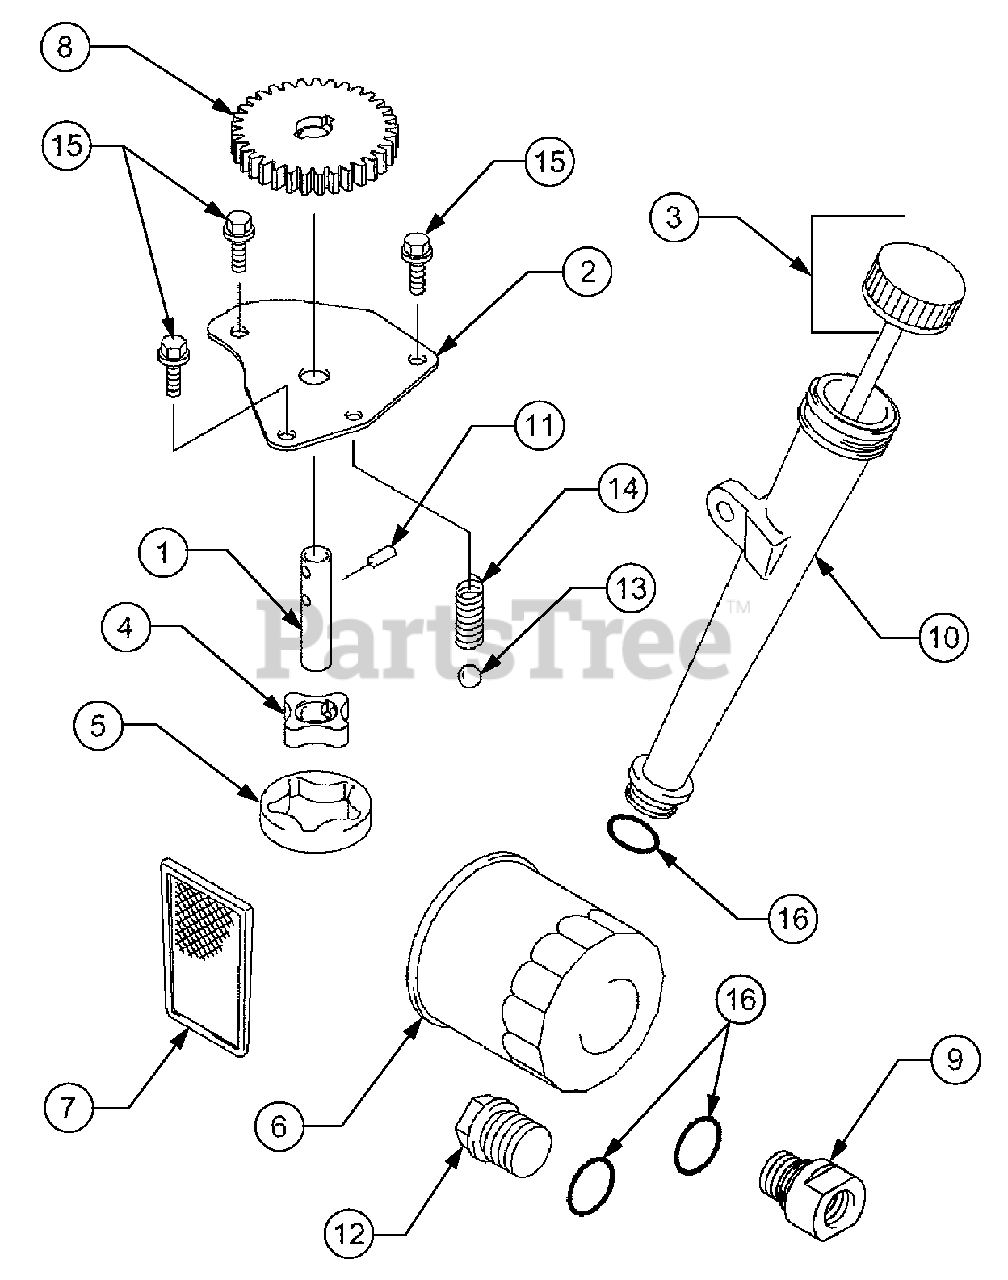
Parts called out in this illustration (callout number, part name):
1	Shaft
3	Cap Assy
4	Rotor, Pump - In
5	Rotor, Pump - Out
6	Filter, Oil
7	Filter, Oil
9	Joint
11	Pin
12	Plug
15	Bolt, Flanged
16	O Ring,16mm
